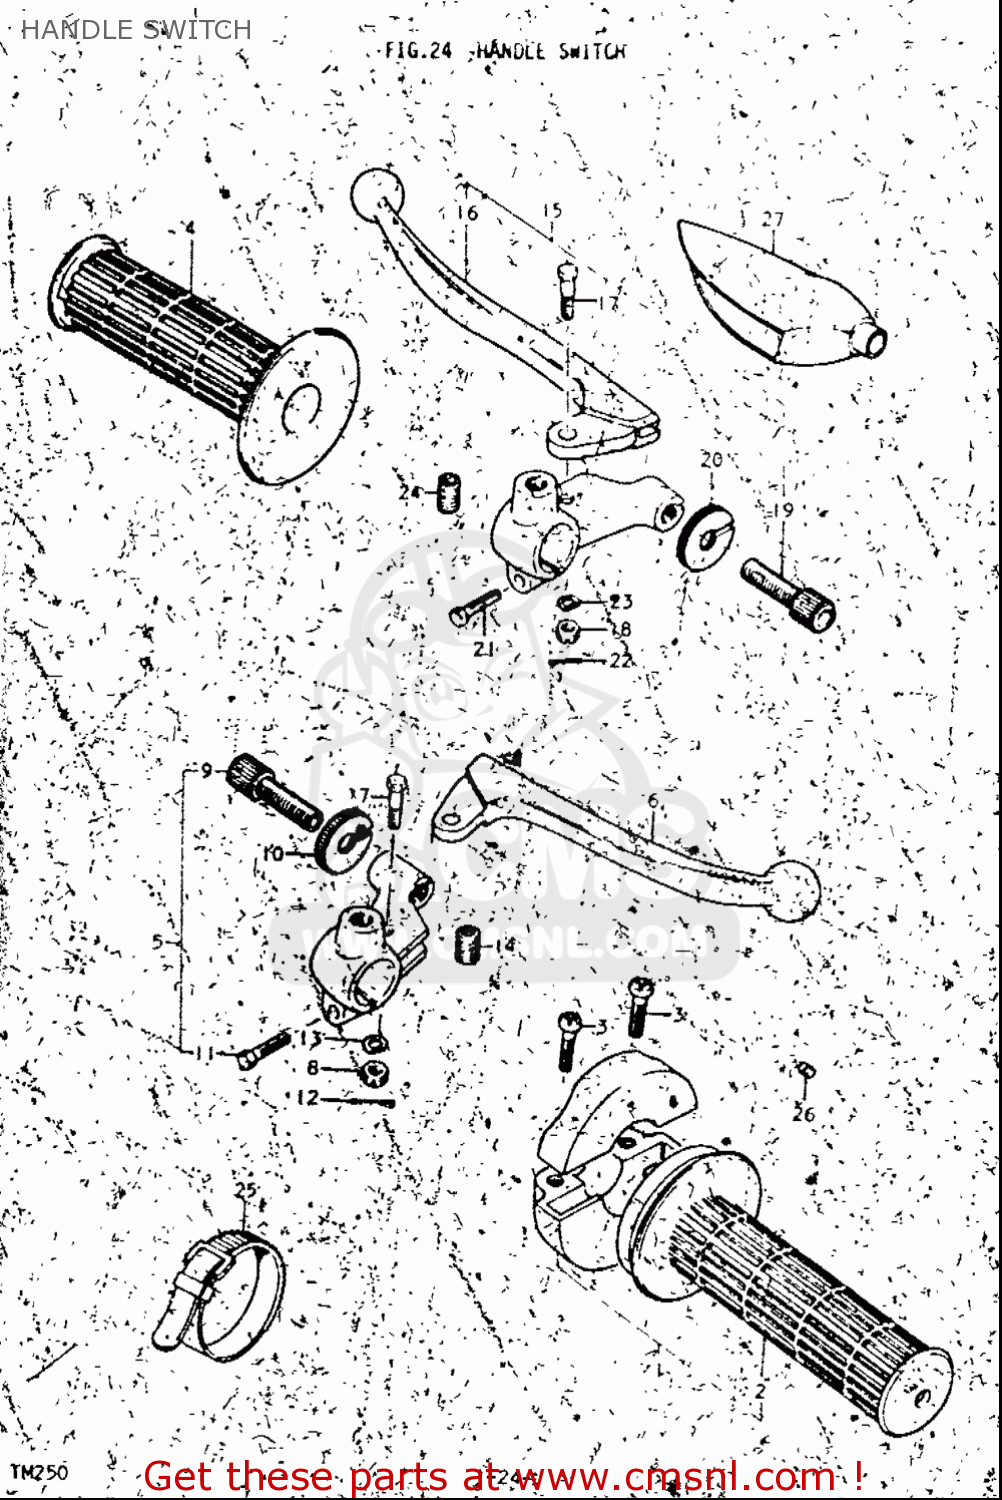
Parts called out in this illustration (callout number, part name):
3	SCREW
5	BRAKE LEVER & SWITCH ASSY
6	LEVER,BRAKE
7	BOLT,LEVER PIVOT
8	NUT,LEVER FITTNG
9	ADJUSTER,CABLE
10	NUT,CABLE ADJUSTER
11	BOLT
12	PIN 16X20
13	WASHER,LOCK
15	LEVER ASSY,CLUTCH
16	LEVER,CLUTCH
17	BOLT,LEVER PIVOT
18	NUT,LEVER FITTNG
19	ADJUSTER,CABLE
20	NUT,CABLE ADJUSTER
21	BOLT
22	PIN 16X20
23	WASHER,LOCK
25	CLAMP(L:120)
26	PIECE,THROTTLE END
27	COVER,CLUTCH LEVER
